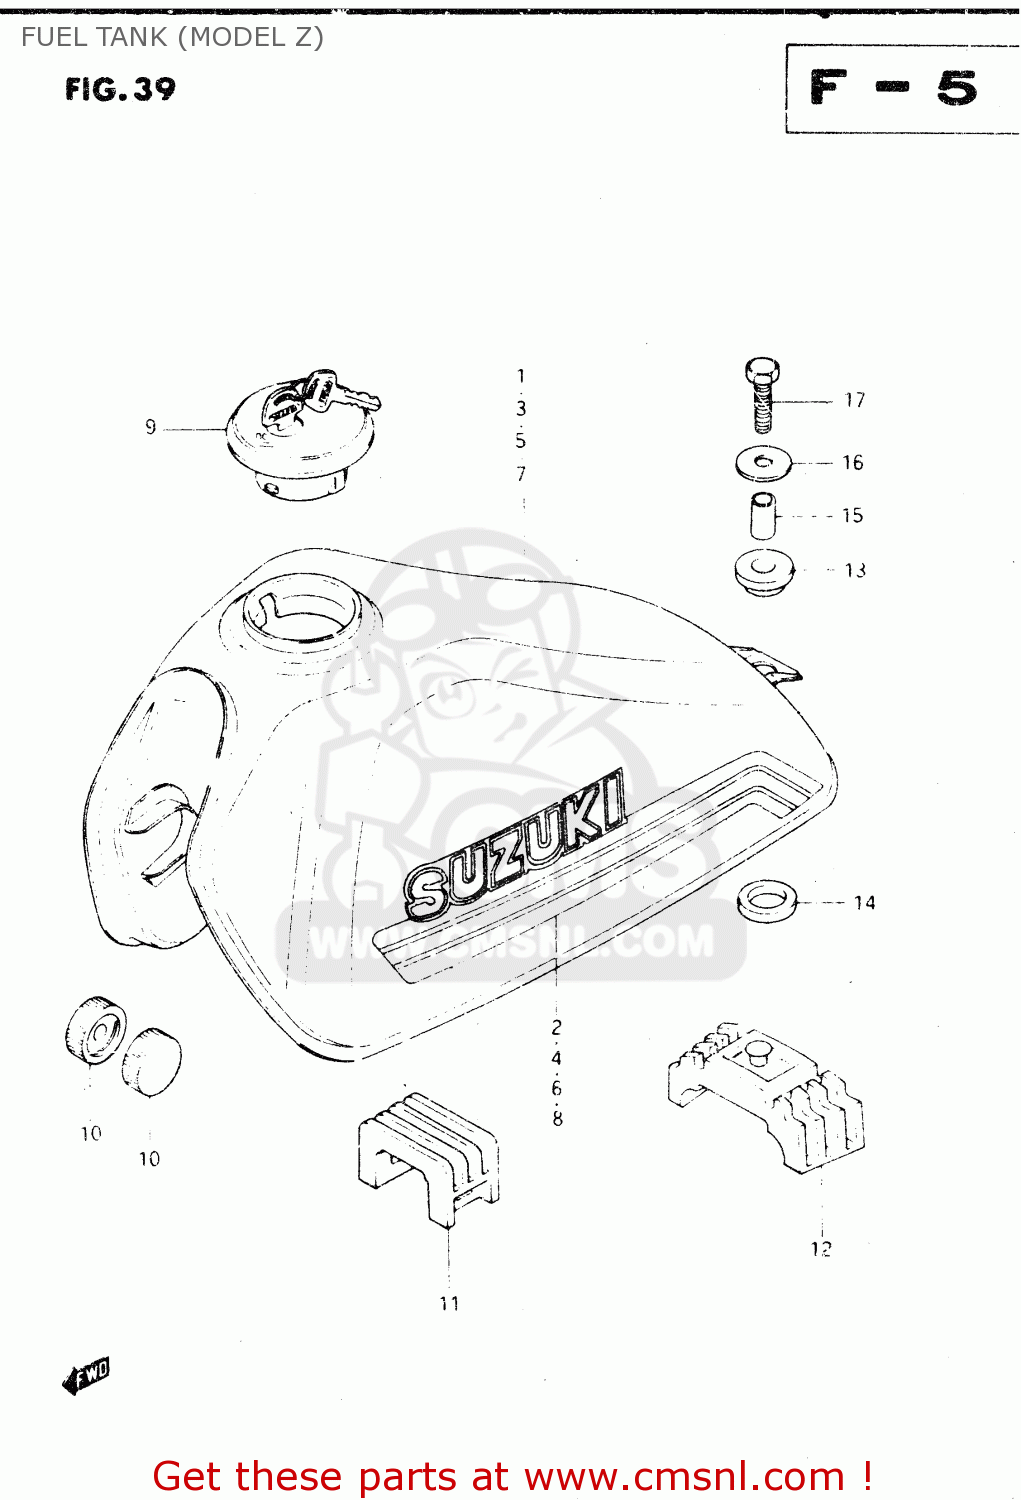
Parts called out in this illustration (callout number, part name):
1	TANK, FUEL (BLACK)
2	TAPE SET
3	TANK, FUEL (BLUE)
4	TAPE SET
5	TANK, FUEL (YELLOW)
6	TAPE SET,FUEL TANK
7	TANK, FUEL (RED)
8	TAPE SET
9	CAP SET,FUEL TANK
10	CUSHION
11	CUSHION,TANK UPR FR
12	CUSHION,FUEL TANK,REAR
13	CUSHION
14	CUSHION
15	SPACER(8.5X12X19)
16	WASHER (8.5X29X1.6)
17	BOLT (8X30)
